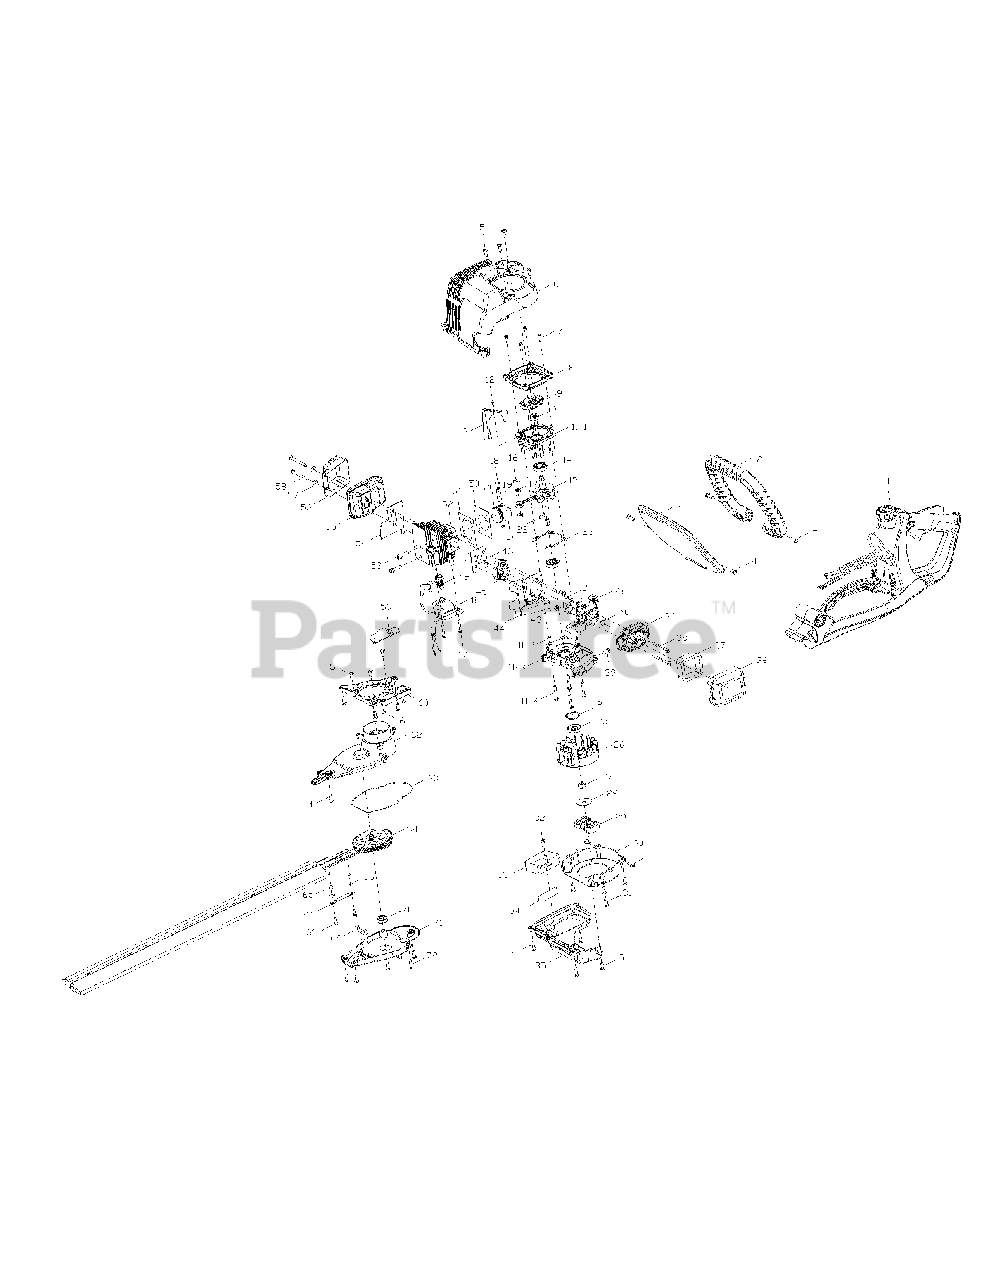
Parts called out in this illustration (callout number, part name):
1	HOUSING ASS'Y
3	GUARD
5	SCREW
6	STARTER HOUSING ASS'Y
7	SCREW
8	CONNECT CASE
11	CRANK CASE ASS'Y
11-1	CRANK CASE (STARTER)
11-2	PIN
11-3	CRANK CASE (FLYWHEEL)
11-4	SCREW
12	SCREW
13	BAFFLE CYLINDER
14	BALL BEARING
15	CRANK ASS'Y
16	SPACER, PISTON
17	NEEDLE BEARING
19	PIN PISTON
20	PISTON RING
21	PISTON
22	KEY (FLYWHEEL)
23	CRANK CASE GASKET
24	C-CLIP
25	OIL SEAL
27	SPACER
28	WASHER
30	CRANK CASE COVER
32	SCREW
33	BAFFLE
34	BAFFLE
35	ENGINE COVER
36	AIR CLEANER ASS'Y
37	FILTER AIR
39	SCREW
40	O-RING (AIR)
41	CARBURETOR
42	GASKET (CARBURETOR)
44	PLATE
45	INSULATOR
46	GASKET (INSULATOR)
48	IGNITION ASS'Y
50	GASKET CYLINDER
51	GASKET CYLINDER
54	GASKET MUFFLER
55	MUFFLER ASS'Y
56	BAFFLE
58	SCREW
59	COVER
61	SCREW
63	WASHER
64	GEAR ASS'Y
65	SPACER
66	WASHER
67	STEEL BOARD
69	FELT
71	PLATE
72	SCREW
